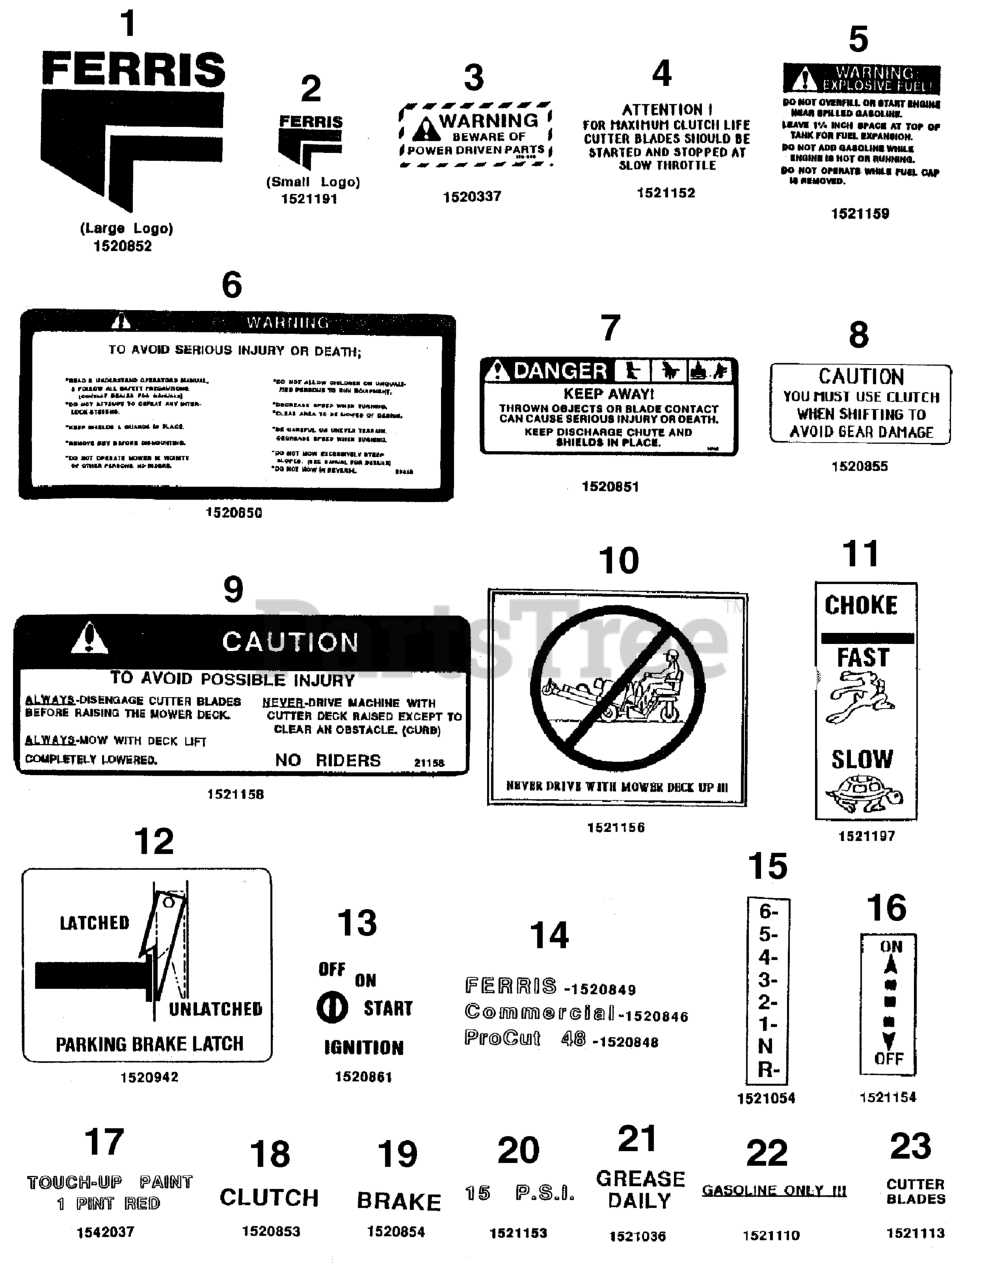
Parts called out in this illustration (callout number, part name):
1	DECAL, Ferris Logo, 10-3/4"
2	DECAL, Ferris Logo (Small)
3	DECAL, Warning
4	DECAL, Attention Belt Life
5	DECAL, EXPLOSIVE FUEL
6	DECAL, WARNING Operation
7	DECAL, DANGER DO NOT OPERATE W/O DEFLECT
8	DECAL, CAUTION Gear Damage
10	DECAL, Never Drive With Mower Deck Up
11	DECAL, Throttle Control
12	DECAL, Parking Brake Latch
13	DECAL, Ignition
14	DECAL, FERRIS TEXT & LOGO
14	DECAL, Commercial
14	DECAL, Word, PROCUT 48
15	DECAL, Shift Pattern
16	DECAL, PTO Switch
17	DECAL, Touch-Up Paint
18	DECAL, Clutch, Word
19	DECAL, Brake, Word
20	DECAL, 15 P.S.I.
21	DECAL, Grease Daily
22	DECAL, Gasoline Only
23	DECAL, PTO Switch
